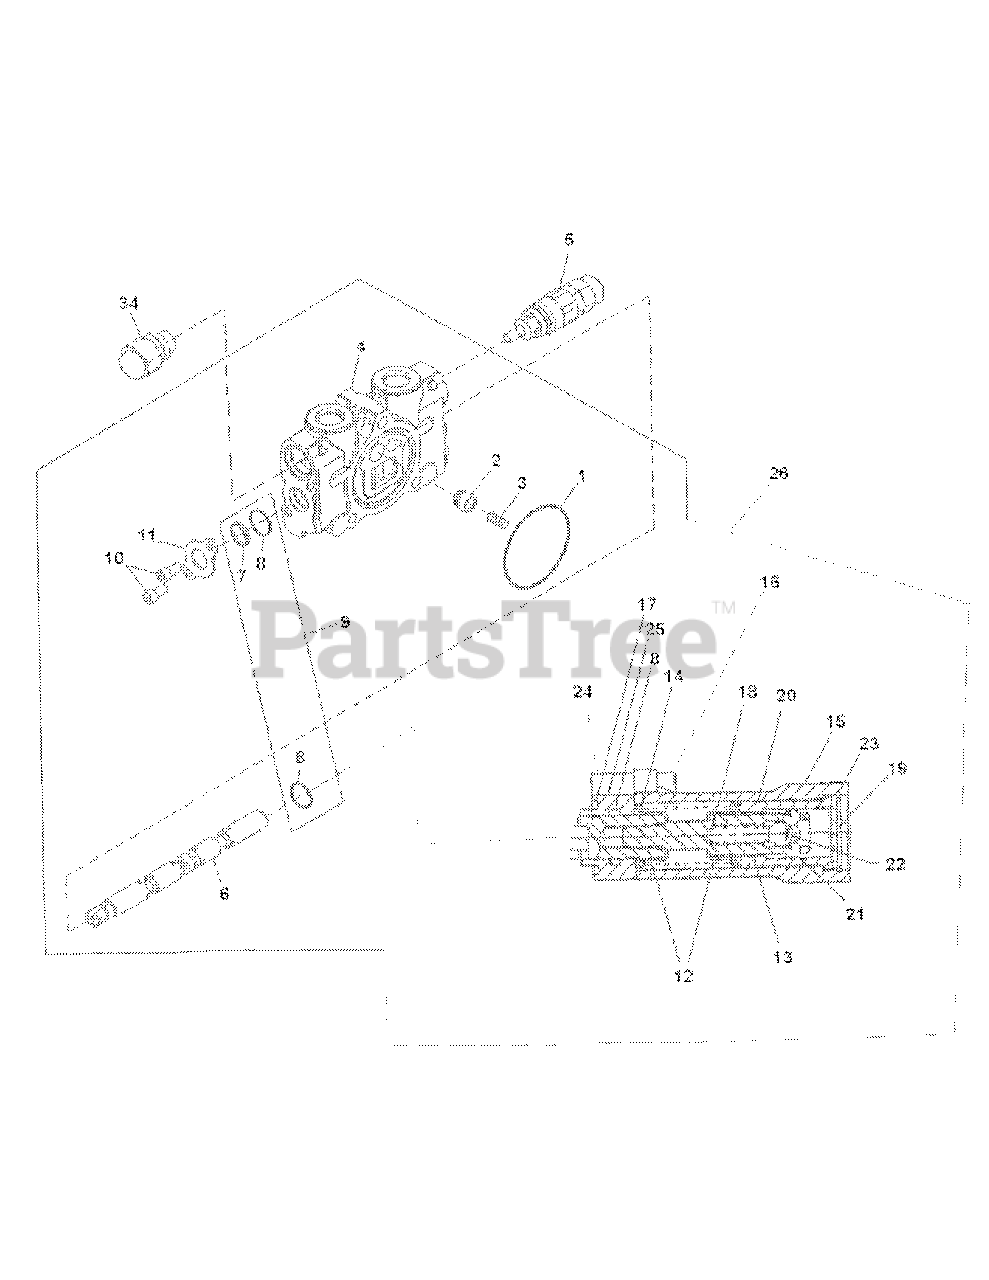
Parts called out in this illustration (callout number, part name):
1	O-Ring
2	Poppet, Load Check
3	Spring, Load Check
4	Valve Section
5	Relief, Work Port 2800 psi
7	Wiper, Spool
8	O-Ring, Spool
9	Seal Kit, Minor (contains two of Item 7 & 8)
10	Cap Screws, Socket Head
11	Plate, Retainer
12	Seat, Spring
13	Screw, Spring Seat
14	Spring, Spool Centering
15	Cap, Spring Spool
16	Cap Screws, Socket Head
17	O-Ring
18	Spring, Detent
19	Spacer, Cap
20	Sleeve, Non-Detent
23	Ring, Retaining
24	Spacer, Cap Screw
25	Spacer
26	Valve Section Assembly (less Item 5 & 34)
27	Seal Kit, Major
28	Load Check Poppet Kit
29	Spring Centered Spool Positioner Kit
31	Seal Kit, Work Port Relief
33	Restrictor Assembly - .073" Diameter
34	Plug, Shut Off
